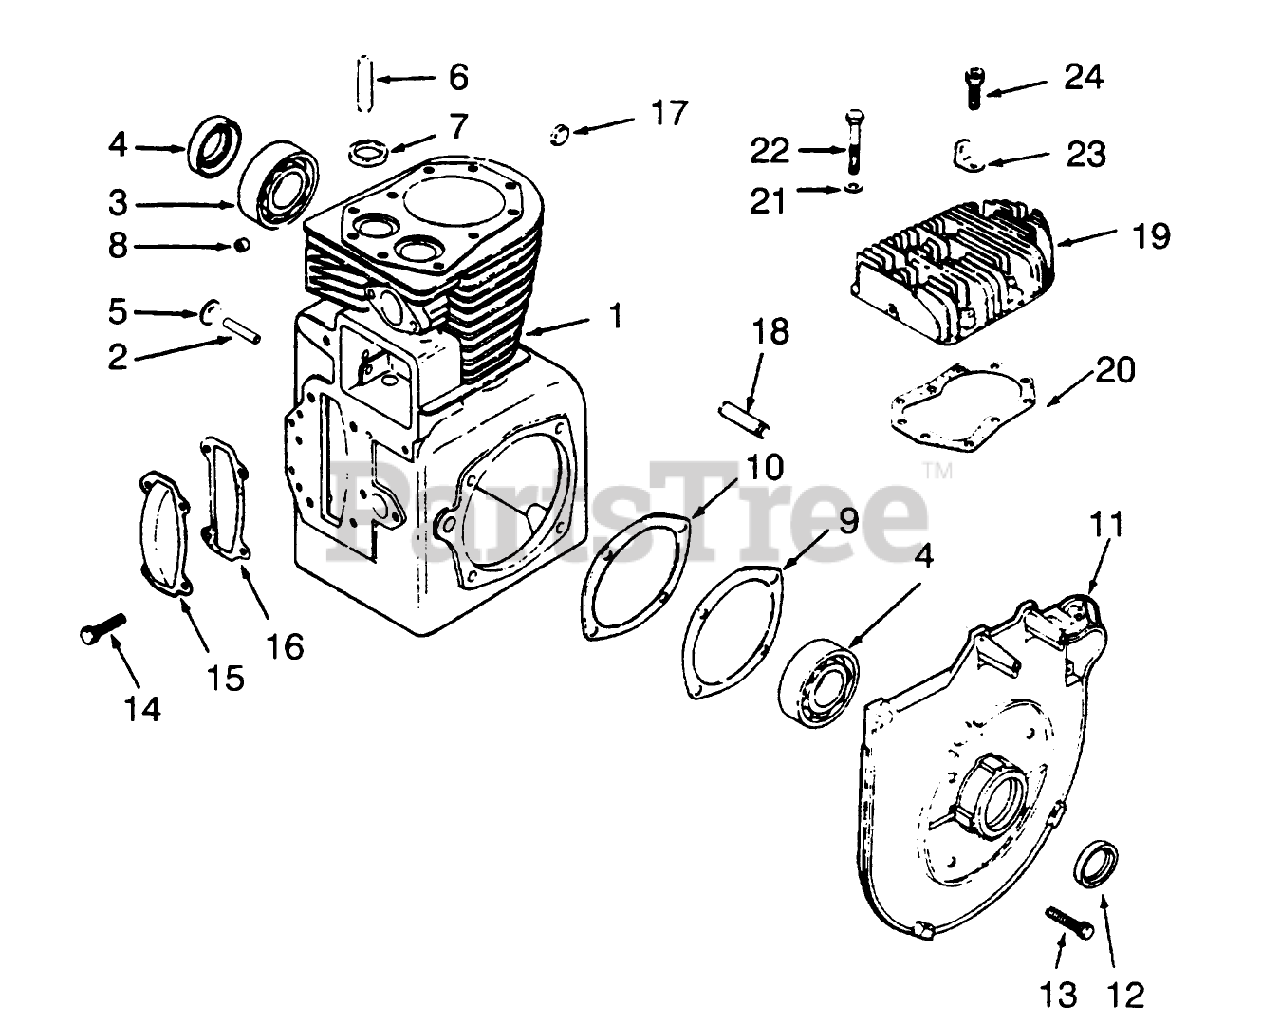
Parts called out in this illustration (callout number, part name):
1	VNDR #77-522-60
2	VNDR #235125-S
3	KOHLER 235376
4	KOHLER 47-032-07
5	KOHLER X-230-11
6	VNDR #235007-S
7	KOHLER 230265
8	KOHLER 234866
9	KOHLER 47-041-09
10	KOHLER 47-522-05
11	KOHLER 47-146-11
12	KOHLER 47-032-06
13	KOHLER X-159-2
14	KOHLER X-132-6
15	KOHLER 235026
16	KOHLER 235025
18	KOHLER 236559
19	KOHLER 47-015-06
20	KOHLER 47-041-15
21	KOHLER 270889
22	KOHLER 270158
23	KOHLER 47-455-02
24	KOHLER 47-086-17
